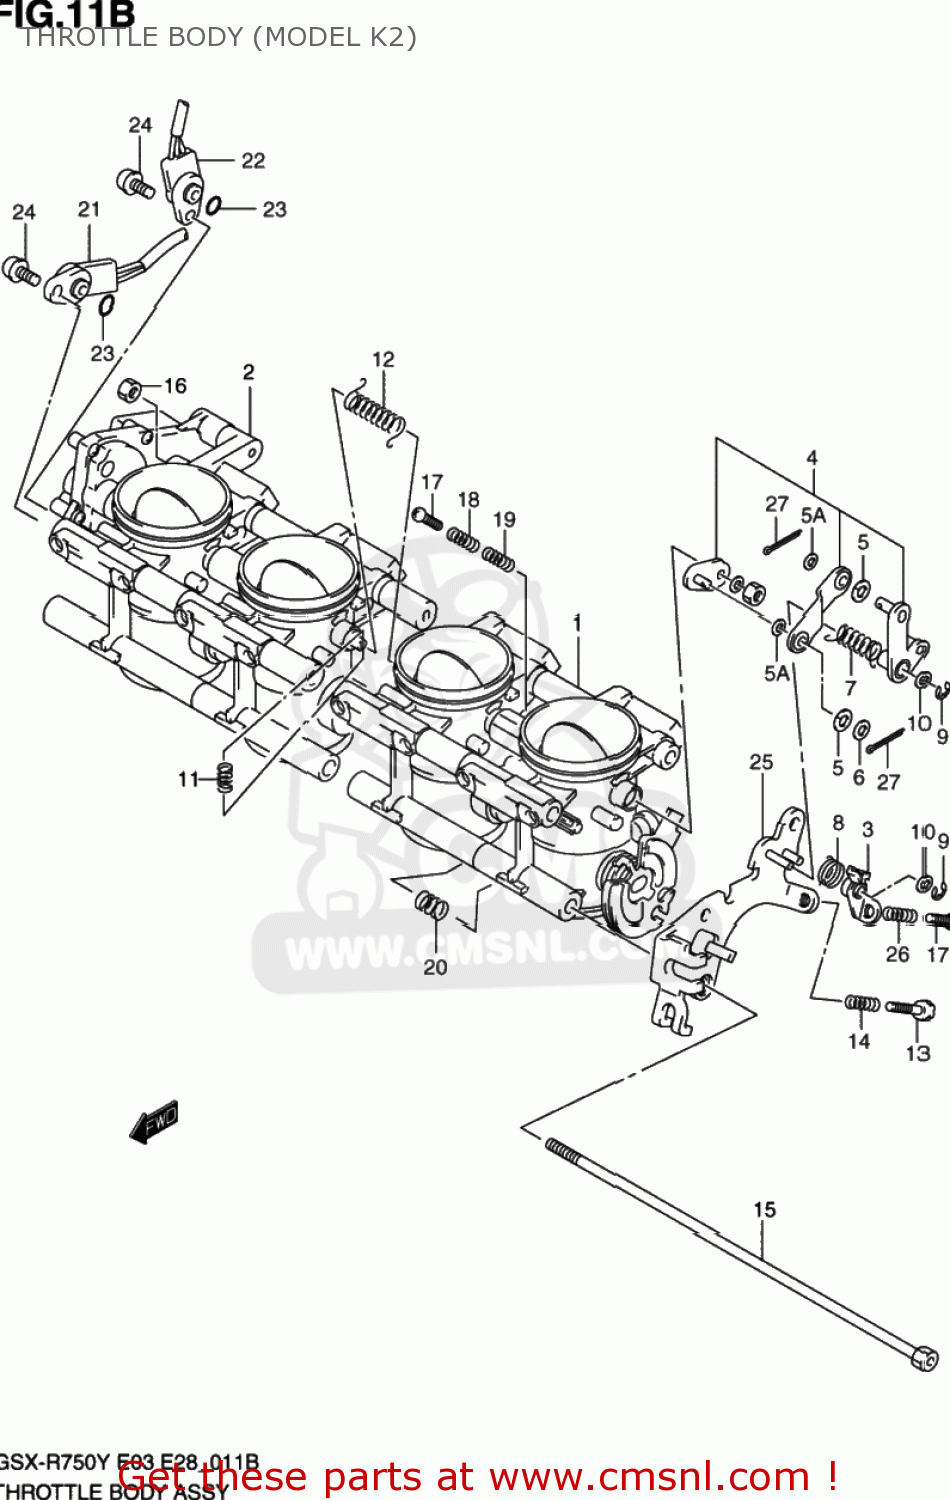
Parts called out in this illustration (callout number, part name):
1	BODY SET,THROT
2	BODY SET,THROTTLE #3/#4
3	LEVER,LINK
4	LINK LEVER SET
5	WASHER
5A	WASHER
6	WASHER
7	SPRING
8	SPRING
9	E CLIP
10	WASHER
11	SPRING
12	SPRING
13	SCREW,STOP
14	SPRING
15	BOLT
16	NUT
17	SCREW,STOP
18	SPRING
19	SPRING
20	SPRING
21	SENSOR ASSY,TH
22	SENSOR ASSY,TH
23	O RING
24	SCREW
25	PLATE,STAY
26	SPRING
27	PIN
